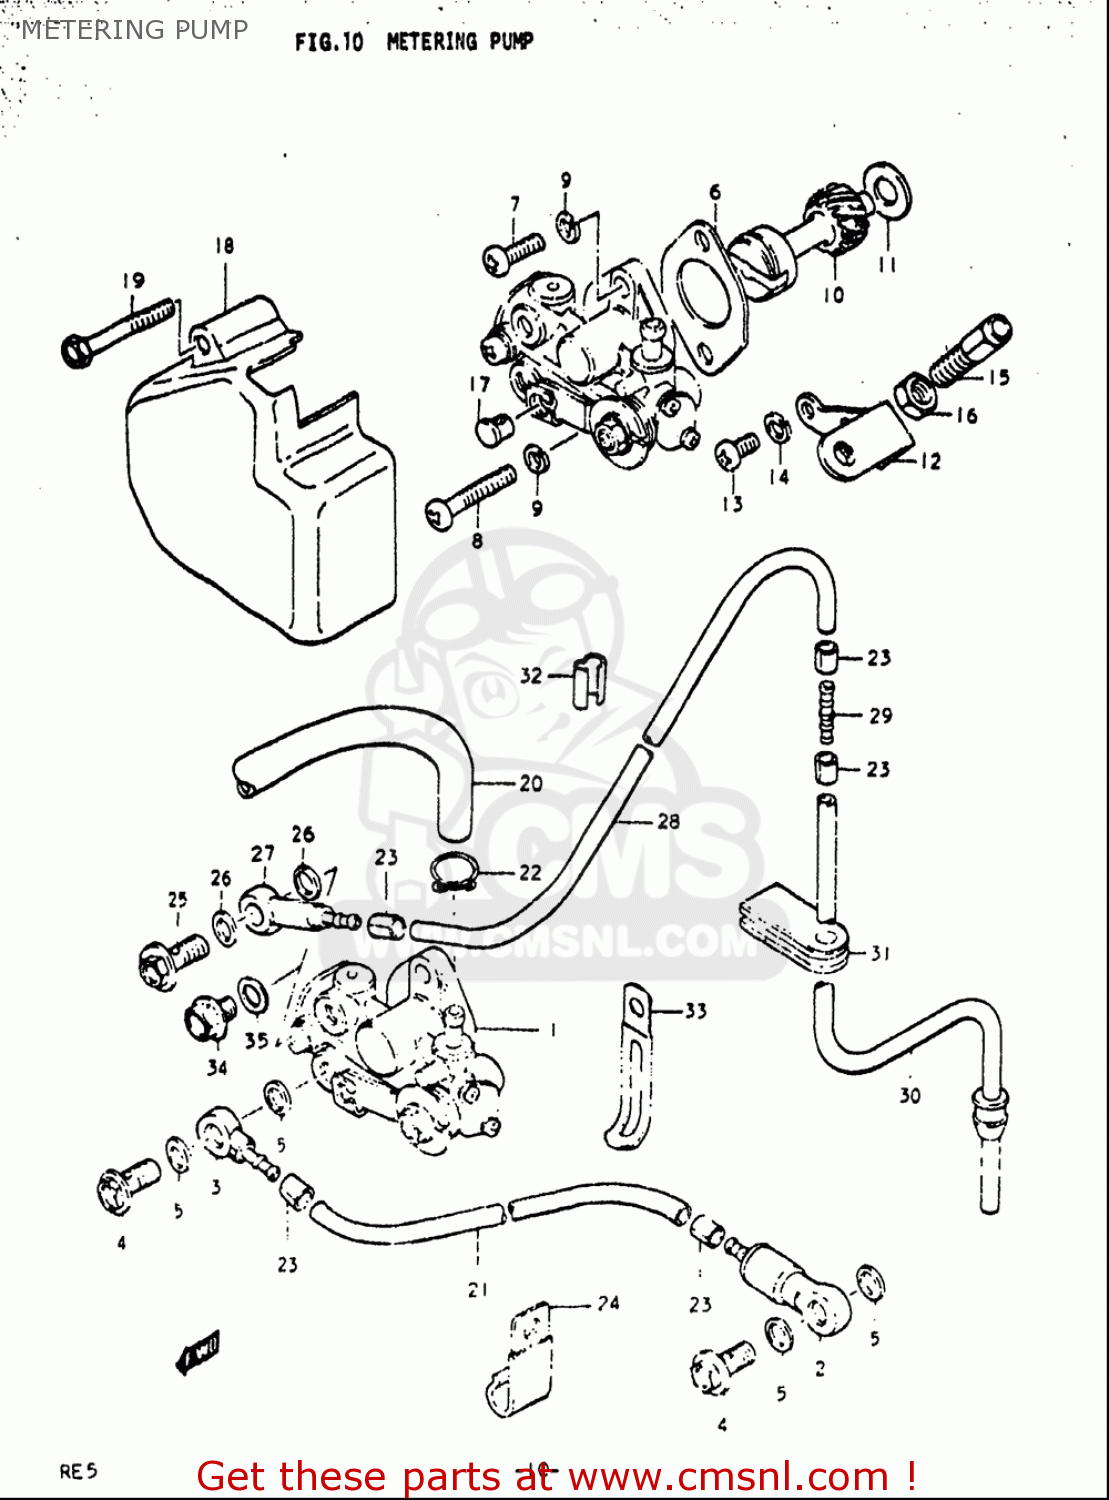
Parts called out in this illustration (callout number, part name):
2	VALVE,CHECK
3	UNION
4	UNION BOLT
5	GASKET(6.2X11X1).2 (NAS)
6	GASKET,OIL PUMP (NAS)
7	SCREW
8	SCREW
9	WASHER,LOCK
13	SCREW
14	WASHER,LOCK
16	NUT
17	TERMINAL,CABLE
19	SCREW
21	HOSE(2X5X600)
22	CLIP
23	CLIP
24	CLAMP
25	UNION BOLT
27	VALVE,CHECK
28	HOSE
32	CLIP
33	CLAMP(L:65)
34	UNION
